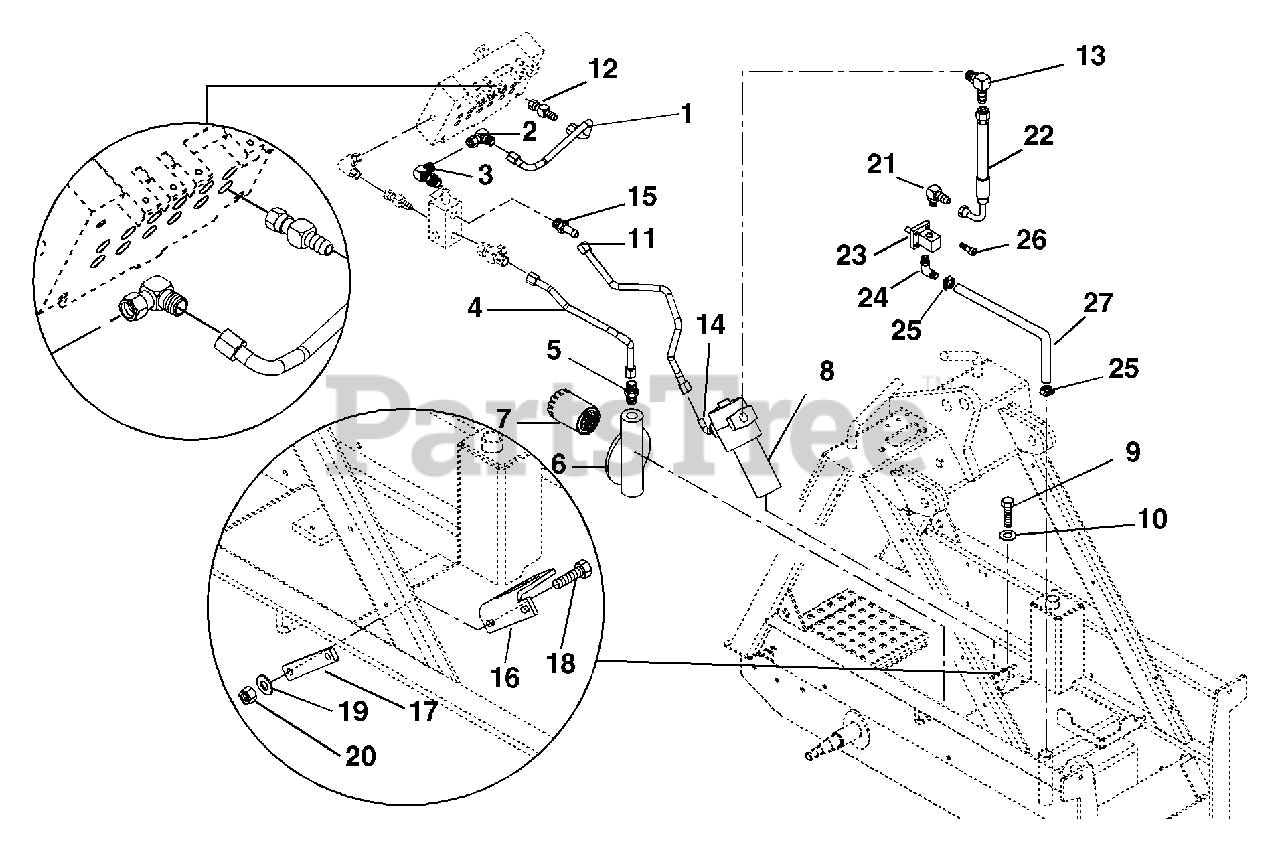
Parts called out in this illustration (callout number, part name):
1	Tube-Valve Bank Inlet
2	Adapter-Swivel Nut 90 Degree Elbow .875-14 x .875-14
3	Adapter-Elbow 90 Degree .75-16 x .875-14
4	Tube-Return
5	Adapter-Connector .875-14 x.750-14
6	Head-Filter
7	Filter-Hydraulic Skidster
8	Filter-Hydraulic Assembly
8	Filter-Element
9	Bolt-Hex .38-16 x 1.00 Grade 5
10	Washer-Flat-Steel .390 x .75 x .125
11	Tube-Filter to Overcenter Valve
12	Adapter-Straight .500-14 x .875-14
13	Adapter-Elbow 90 Degree .750-16 x 1.062-12
14	Adapter-Elbow .875-14 x 1.062-12
15	Adapter-Straight .75-16 x .875-14
16	Bracket, Filter
17	Retainer, Filter Bracket
18	Bolt-Hex M8-1.25 x 65
19	Washer-Flat-Steel .38 x .875 xs .083
20	Nut-Locking-Nylon M8-1.25
21	Adapter-elbow 90 Degree .75-16M x .38-19M
22	Hose-Hydraulic Pump to Filter
23	Seals, Pump
24	Elbow-90 Degree
25	Clamp-Hose
26	Screw-Socket M8-1.25 x 30
27	Hose-Hydraulic Tank to Pump
